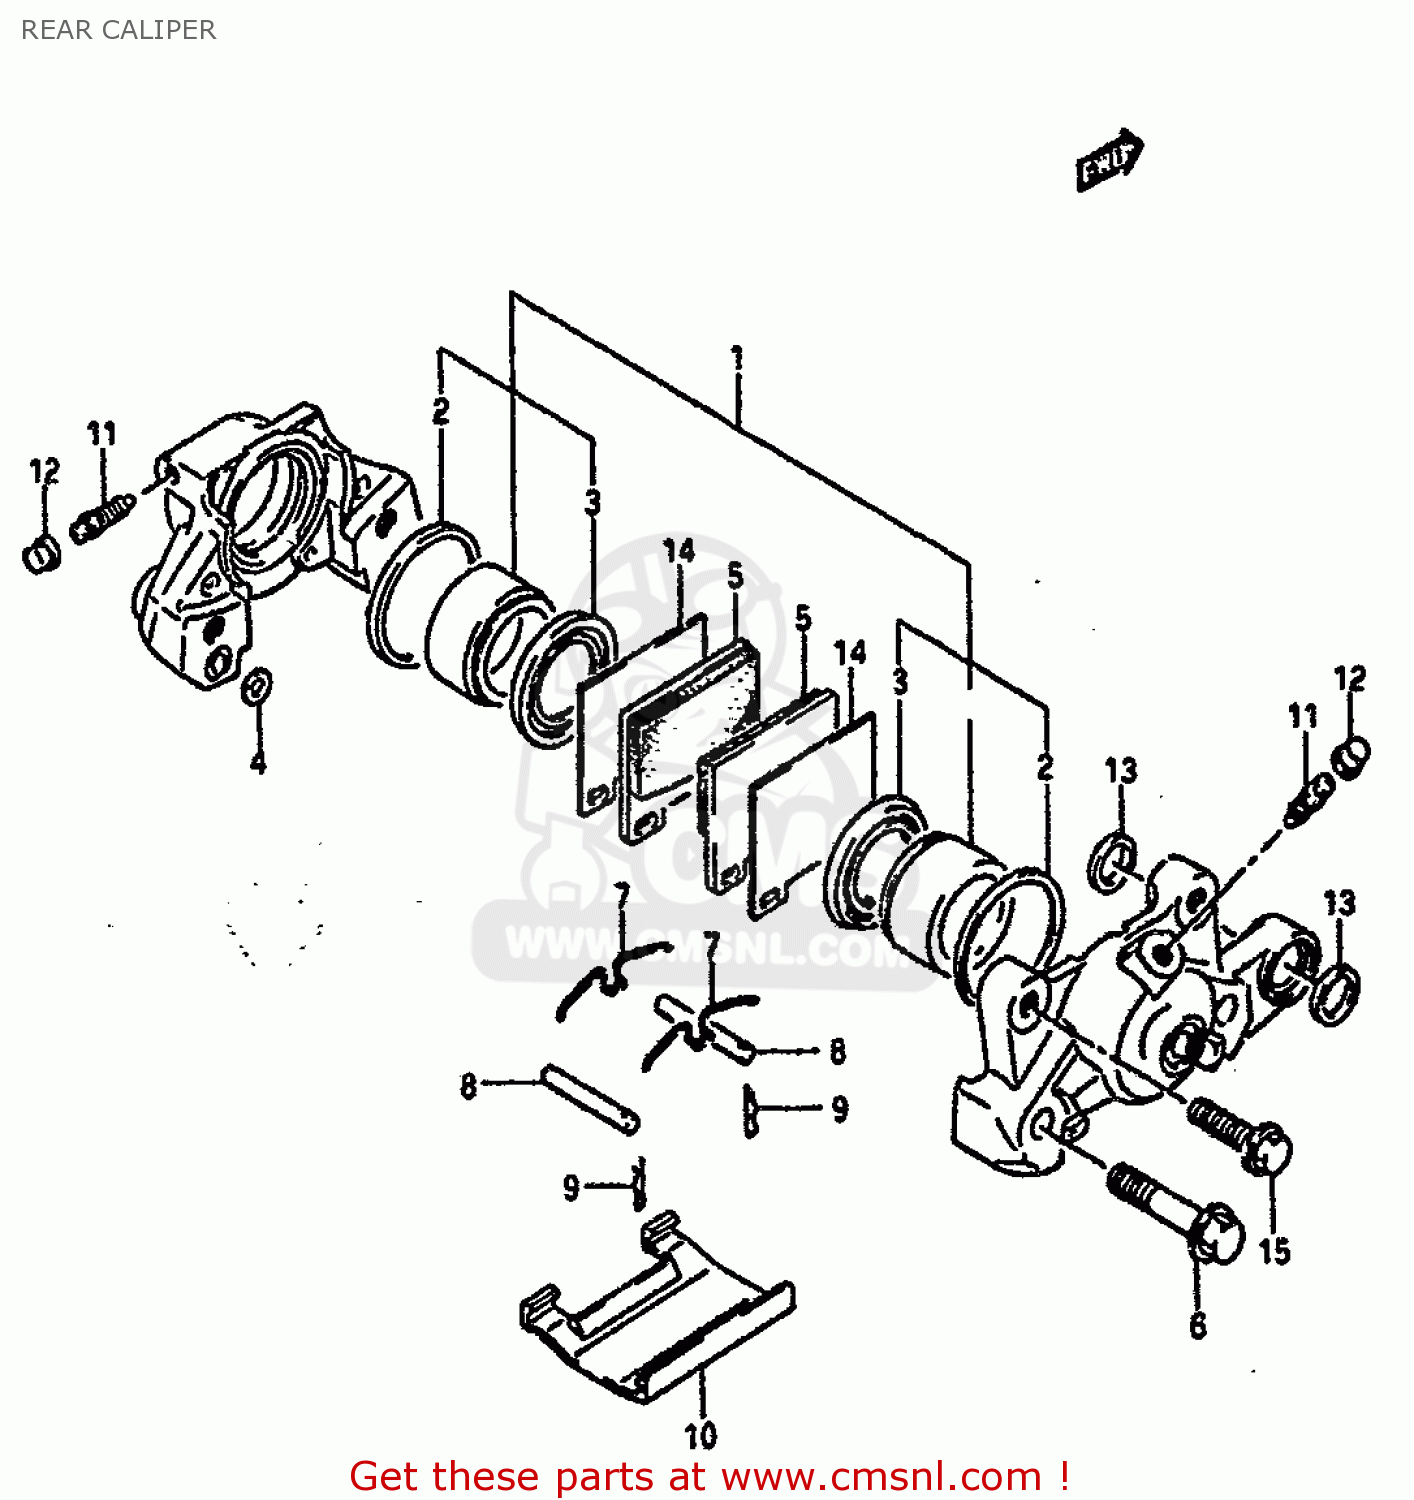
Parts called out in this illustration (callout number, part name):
1	PISTON SET
2	SEAL,PISTON
3	BOOT
4	SEAL,JOINT
5	PAD,BRAKE
6	BOLT
7	SPRING
8	PIN,PAD
9	CLIP,PAD PIN
10	COVER
11	BLEEDER
12	CAP,BREATHER
13	SEAL,RR CUSHION ROD LWR
14	SHIM,PAD
15	BOLT
